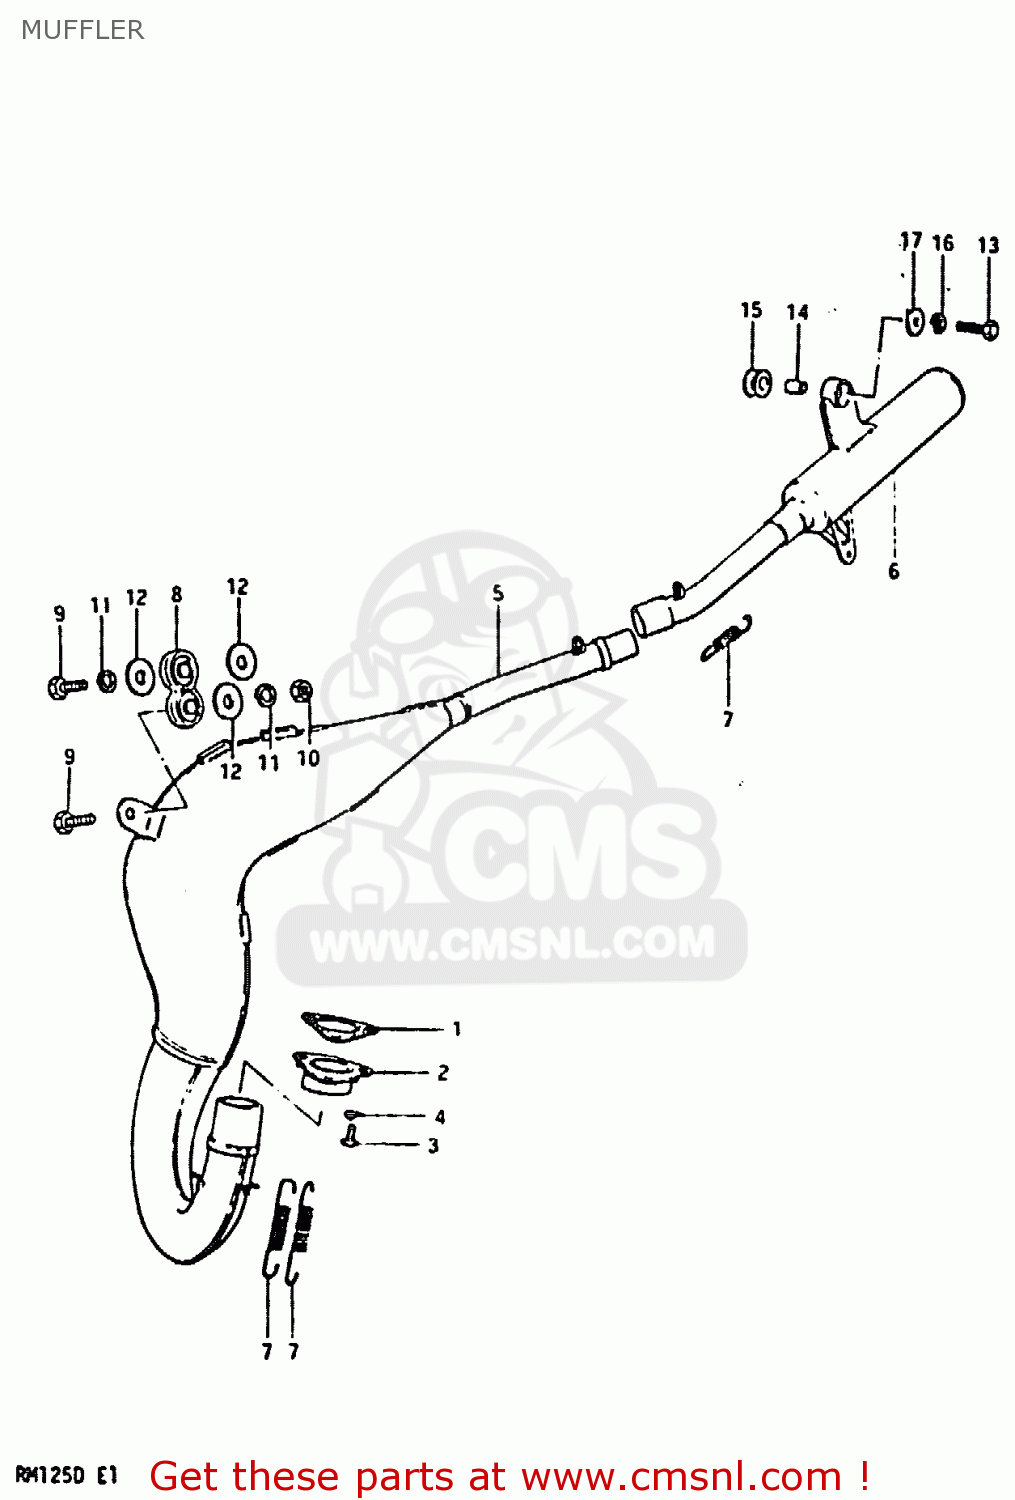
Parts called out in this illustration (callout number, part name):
1	GASKET,EXHAUST PIPE (MCA)
2	FLANGE,EXHAUST PIPE
3	SCREW
4	LOCK WASHER
5	BODY,MUFFLER
6	BODY,MUFFLER
7	SPRING
8	DAMPER,MUFFLER
9	BOLT(8X32)
10	NUT 8MM
11	LOCK WASHER
12	WASHER
13	BOLT(8X32)
14	SPACER (8.6X12X17.5)
15	CUSHION
16	LOCK WASHER
17	WASHER (8.5X29X1.6)
